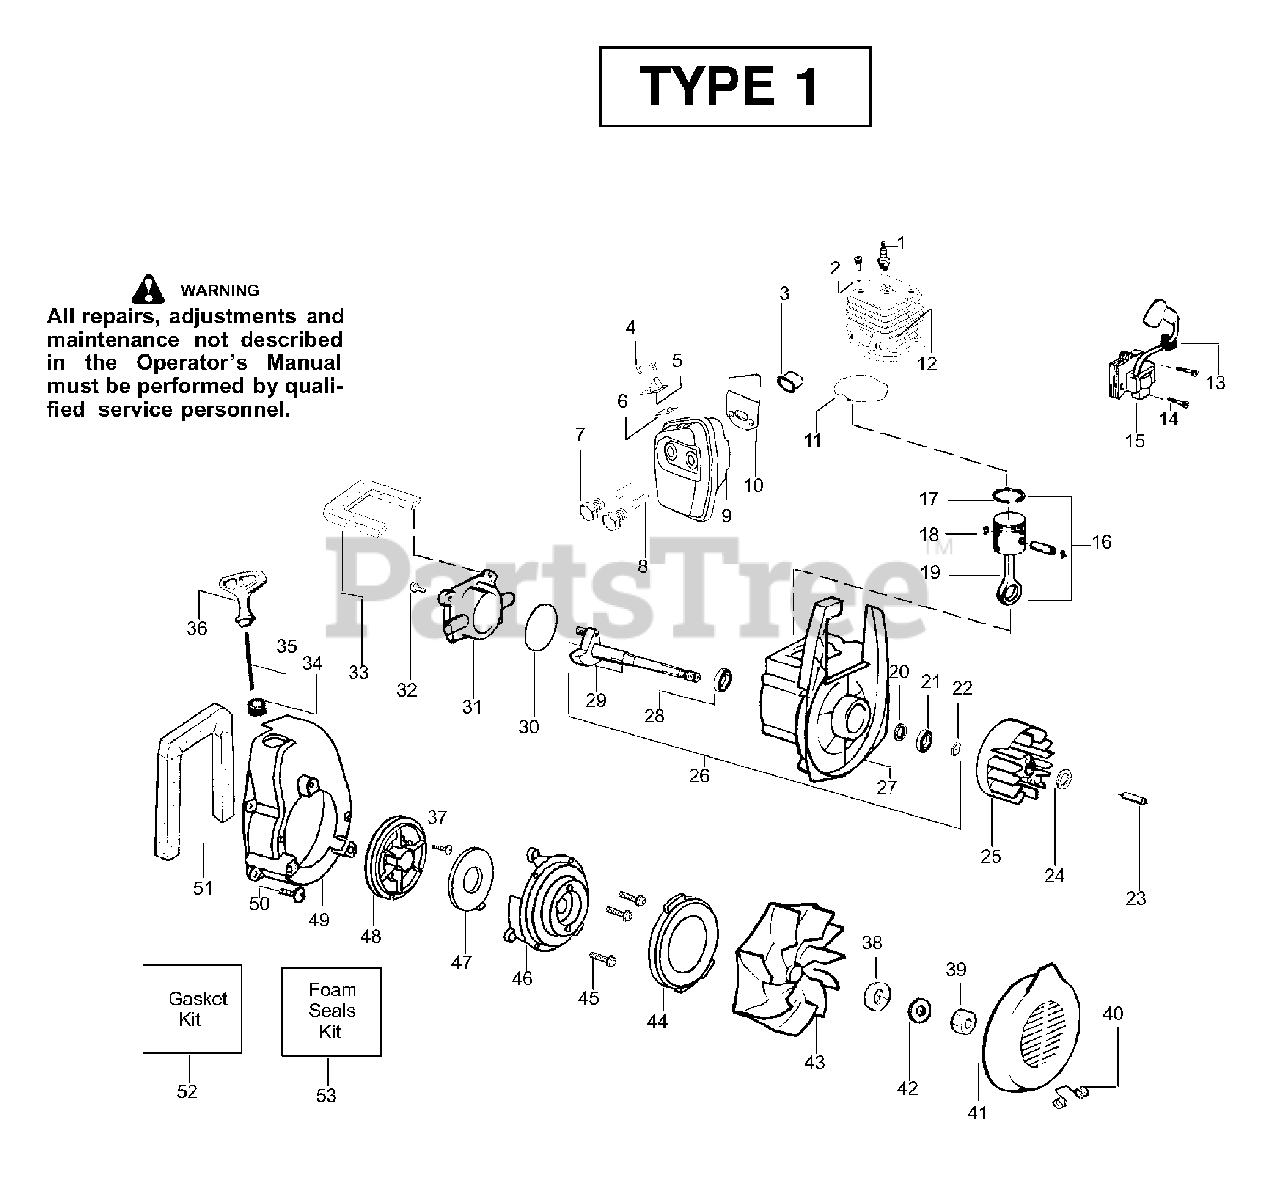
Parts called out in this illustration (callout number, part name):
1	Spark Plug (RCJ-6Y)
3	Insulator-Heat
5	Deflector-Muffler
6	Kit-Spark Screen
7	Bolt-Muffler-external
8	Screw-Muffler-Internal
9	Kit-Muffler
10	Gasket-Baffle (kit)
11	Gasket-Cylinder (kit)
12	Kit-Cylinder
13	Grommet-Ign. Module
14	Screw-Ignition Module
15	Ignition Module
16	Kit-Piston
17	Piston Ring
18	Retainer-Piston Pin
19	Assy-Connecting Rod
20	Seal-Crankcase
21	Bearing-Outer
22	Retainer Ring-C'chaft
23	Spacer-Flywheel
25	Assy-Flywheel
26	Assy-Crankcase/Crankshaft
27	Assy-Crankcase
28	Bearing-Inner
29	Assy-Crankshaft
30	O-ring-C/case (kit)
31	Cover-Crankcase
32	Screw
33	Foam-219mm (kit)
34	Eyelet-Flange
35	Kit-Rope
36	Handle-Starter
37	Screw-Rope
38	Washer-Flat
40	Spring-Return Cover
41	Inlet Door
42	Washer-Belleville
43	Assy-Impeller
44	Seal-Ring
46	Housing-Pulley
47	Spring-Starter
48	Kit-Starter Pulley
49	Fan Housing
50	Screw
51	Foam-365mm (kit)
52	Kit-Gasket
53	Kit-Foam Seals
